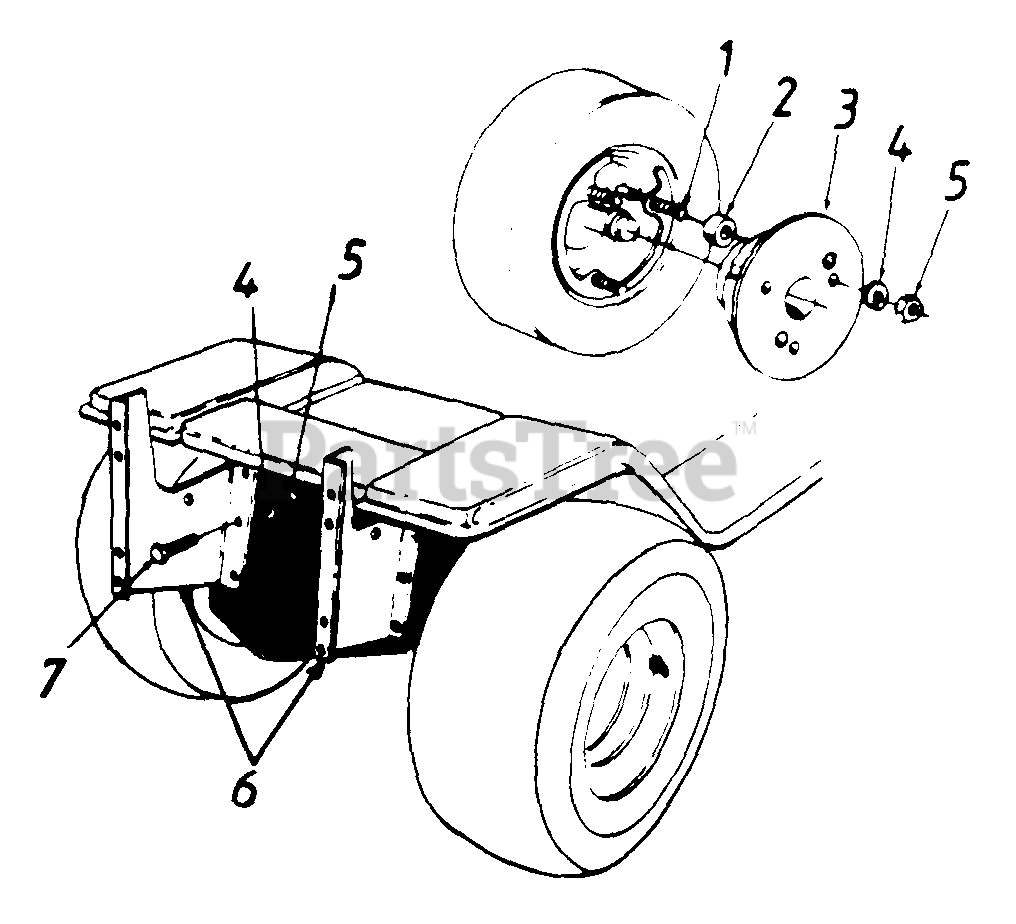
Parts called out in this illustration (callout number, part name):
1	Wheel Weight Snap Ring
3	Wheel Weight
4	L-Wash. 5/16" I.D.
5	Hex Nut 5/16-18 Thd.
7	Hex Bolt 5/16-18 x .75" Lg.
